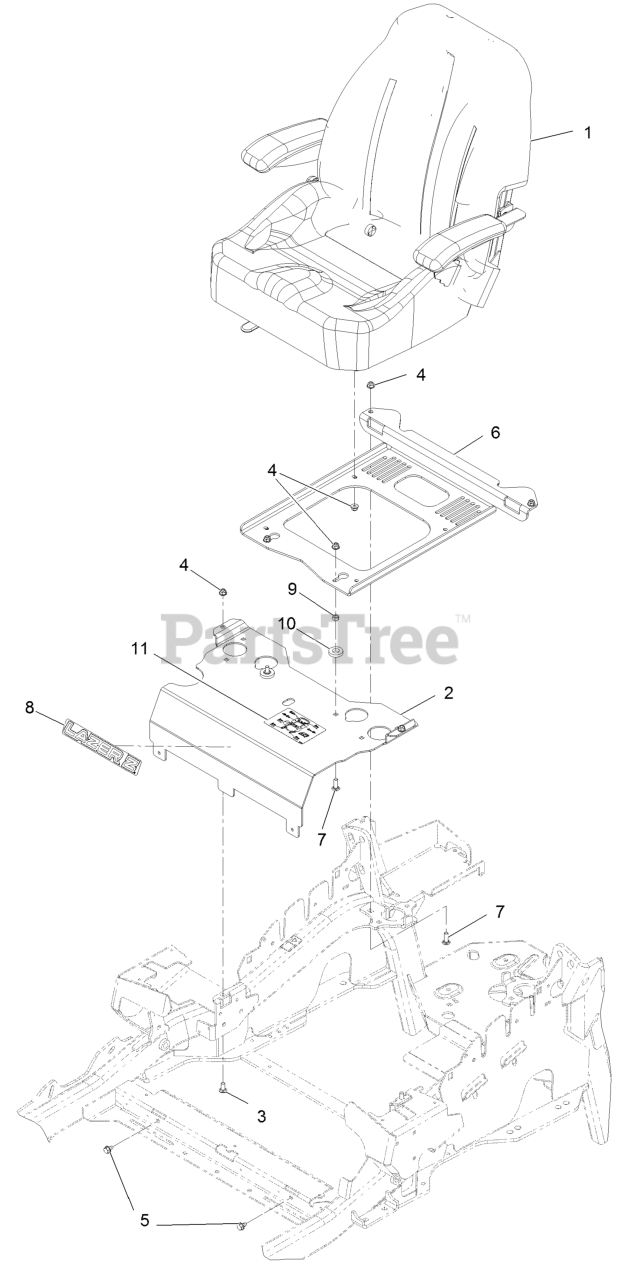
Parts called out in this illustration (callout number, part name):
1	ASM-SEAT LZE
2	Panel-Front, Seat Mount
3	SCREW-CARR
4	NUT-HF, NI
6	PLATE-SUPPORT, SEAT
7	SCREW-CARR
8	DECAL, LAZER MODEL
9	NUT-HEX
11	DECAL-SERVICE AID
